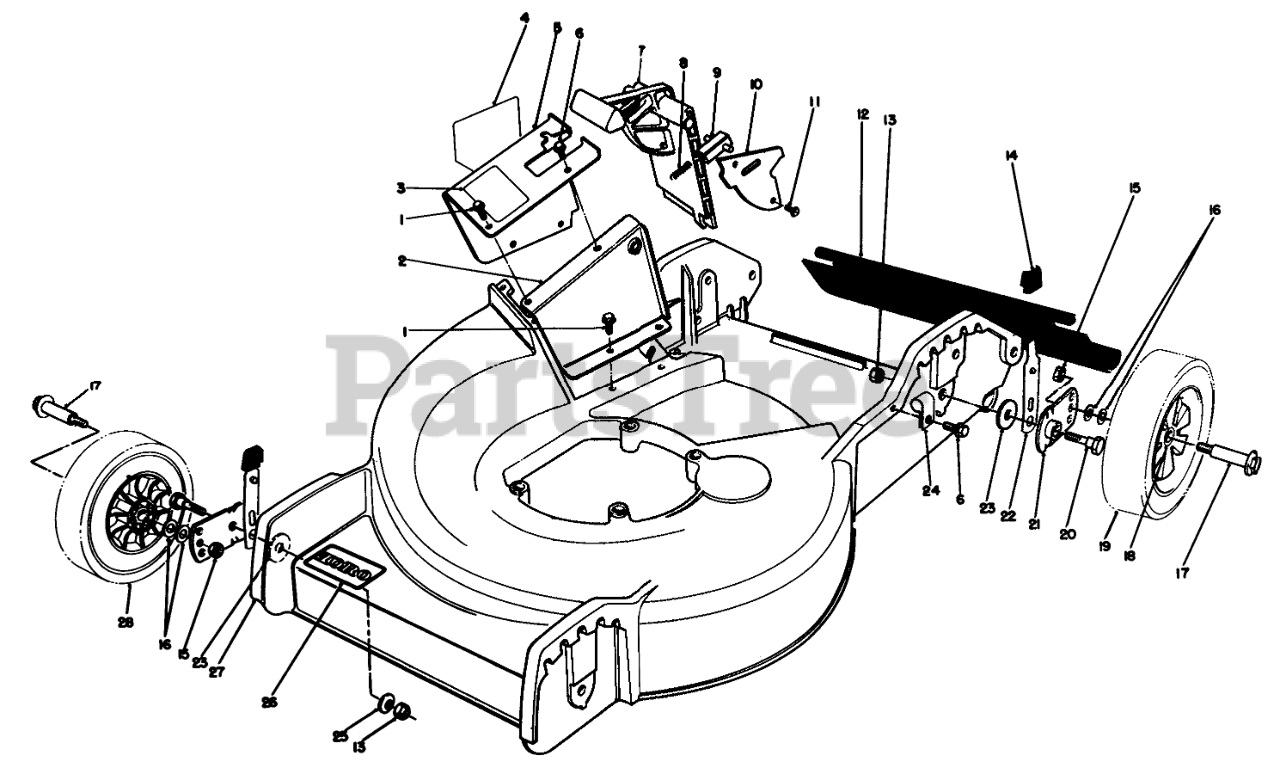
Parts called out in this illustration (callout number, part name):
1	SCREW
2	Tunnel-Inner
3	DECAL - CAUTION
4	Decal-Danger
5	Tunnel-Outer (Incl. Ref. #3 & 4)
6	SCREW
7	Door-Mulching
8	SPRING-COMPRESSION, LATCH
9	Door Latch
10	DOOR COVER
12	SHIELD - TRAILING
13	NUT-LOCK, NI
14	KNOB-ARM
15	Nut
16	WASHER
17	BOLT-WHEEL
18	BUSHING
19	Wheel & Tire Assembly (Incl. Ref #18)
20	5/16-18 PIVOT SCREW
21	PIVOT ARM ASSY
22	SPRING ARM ASM
23	PIVOT WASHER
24	CLAMP-R
25	WASHER-BELLEVILLE
26	DECAL
27	HSG & CARTON
28	Wheel & Tire Assembly (Incl. Ref. #18)
